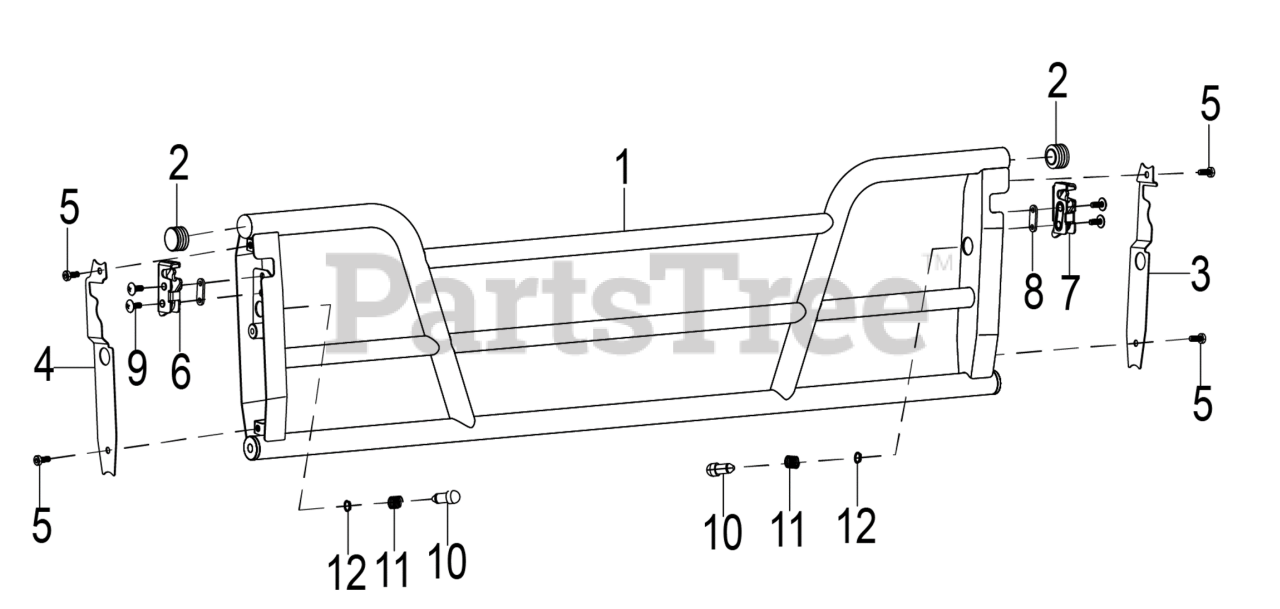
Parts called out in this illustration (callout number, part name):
2	ROUND PLASTIC PLUG
3	TAILGATE PROTECT PLATE (LH)
4	TAILGATE PROTECT PLATE (RH)
5	SOCKET HEX FLAT HEAD BOLT M6X16
6	TAILGATE LOCK (RH)
7	TAILGATE LOCK (LH)
8	DOOR LOCK ADJUSTMENT GASKET
9	HEX FLANGE BOLT M6X25
10	SLOTTED PIN 16 x 38
11	COMPRESSION SPRING
